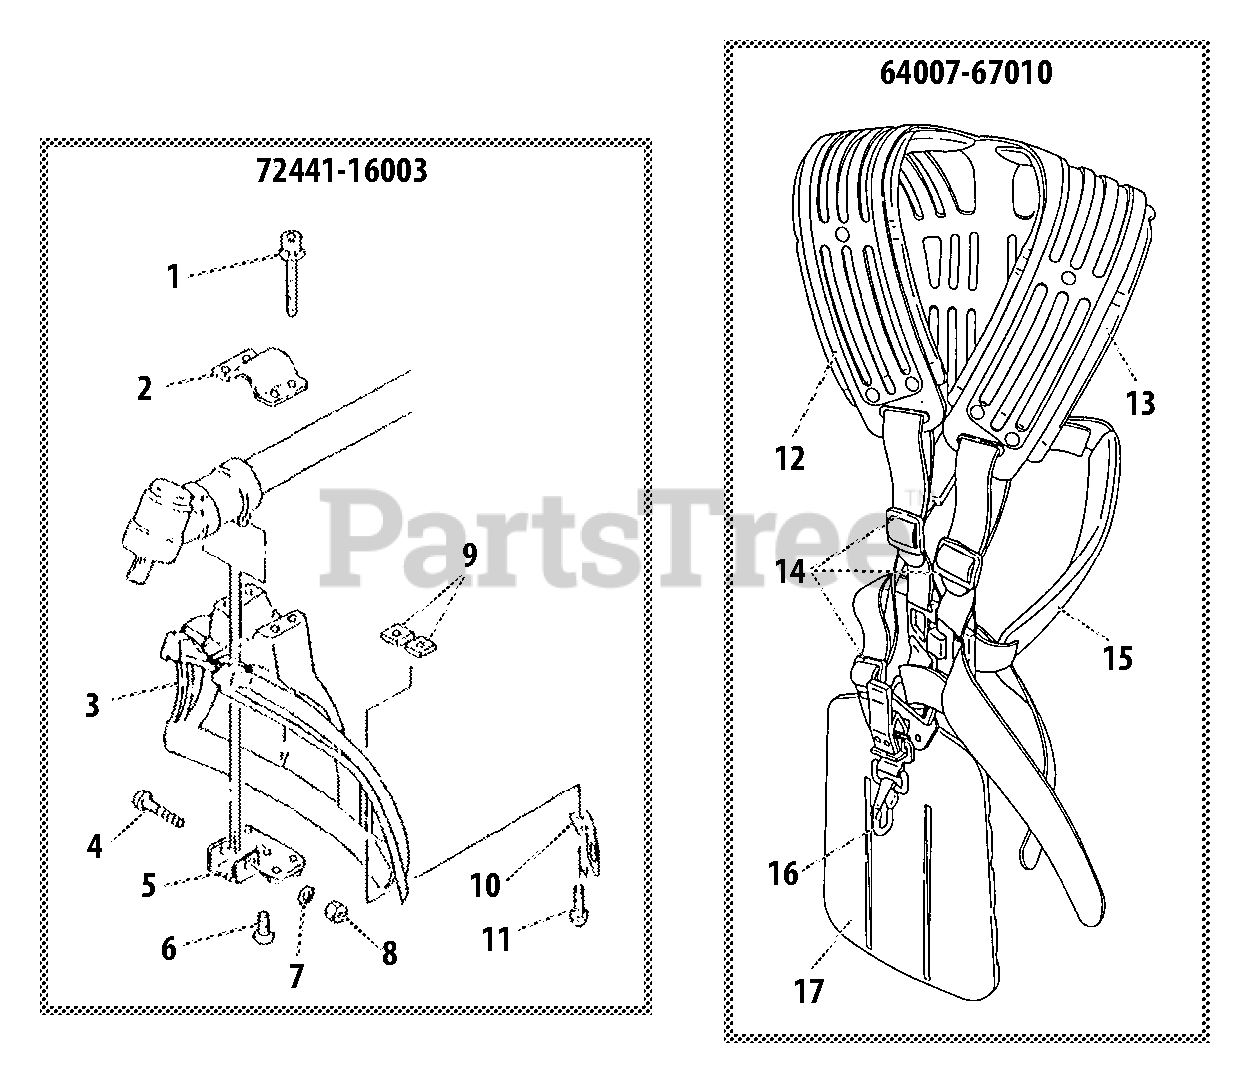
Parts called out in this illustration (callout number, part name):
1	SCREW - 5X45
2	CLAMP - UPPER
3	SHIELD, DEBRIS - BLACK
4	SCREW - 6X40
5	CLAMP - LOWER
6	SCREW
7	WASHER - 6
8	NUT - 6
9	NUT - 5
10	KNIFE, TRIMMER LINE
11	SCREW - 5X16
12	PAD - RIGHT
13	PAD - LEFT
14	BUCKLE
15	PAD
16	HOOK
17	PAD
64007-67010	HARNESS ASSY
72441-16003	DEBRIS SHIELD KIT
